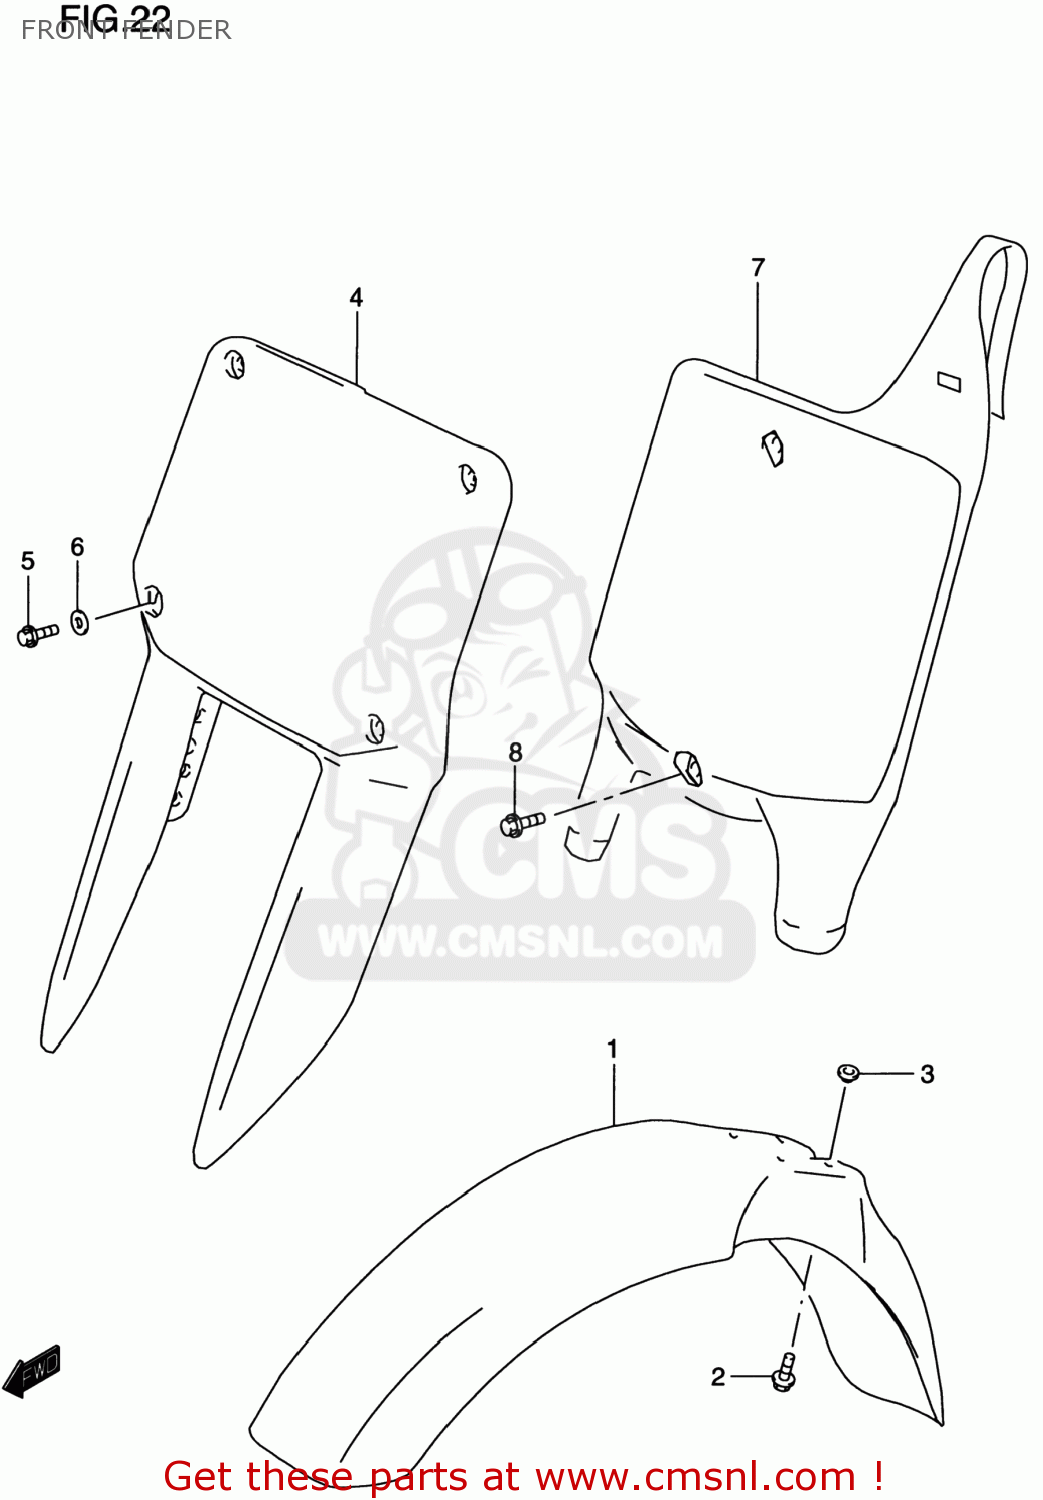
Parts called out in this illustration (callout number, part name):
1	FENDER,FRONT
2	BOLT(6X16)
3	WASHER
4	PLATE,NUMBER FR
5	BOLT
6	WASHER
7	PLATE,NUMBER,FRONT
8	BOLT(6X16)
